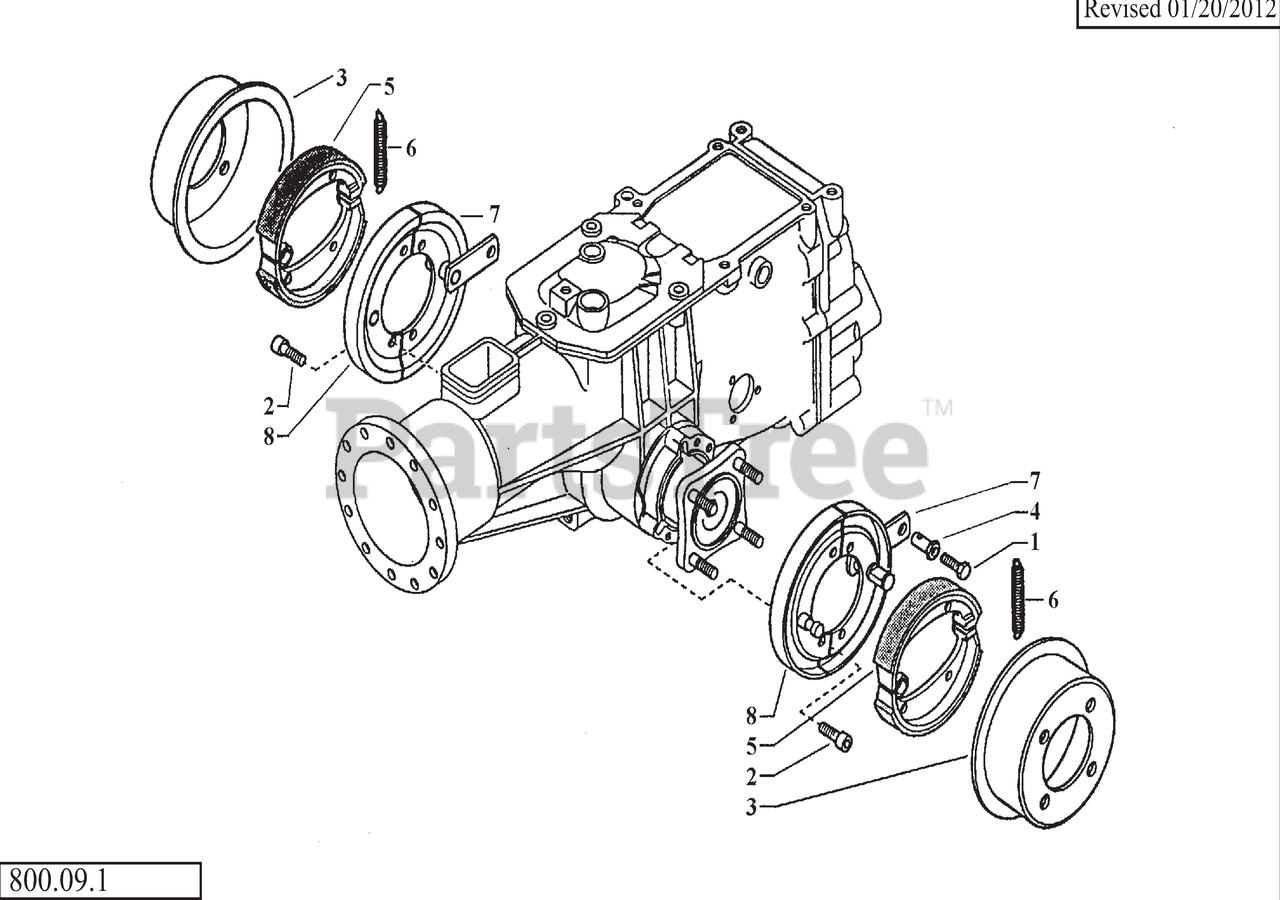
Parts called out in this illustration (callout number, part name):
1	CAP SCREW, M6X14
2	CAP SCREW, M8X25
3	BRAKE DRUM
4	PIN, CABLE CLAMP
5	BRAKE SHOE
6	SPRING
7	LEVER
8	PIN, HALF DISC
